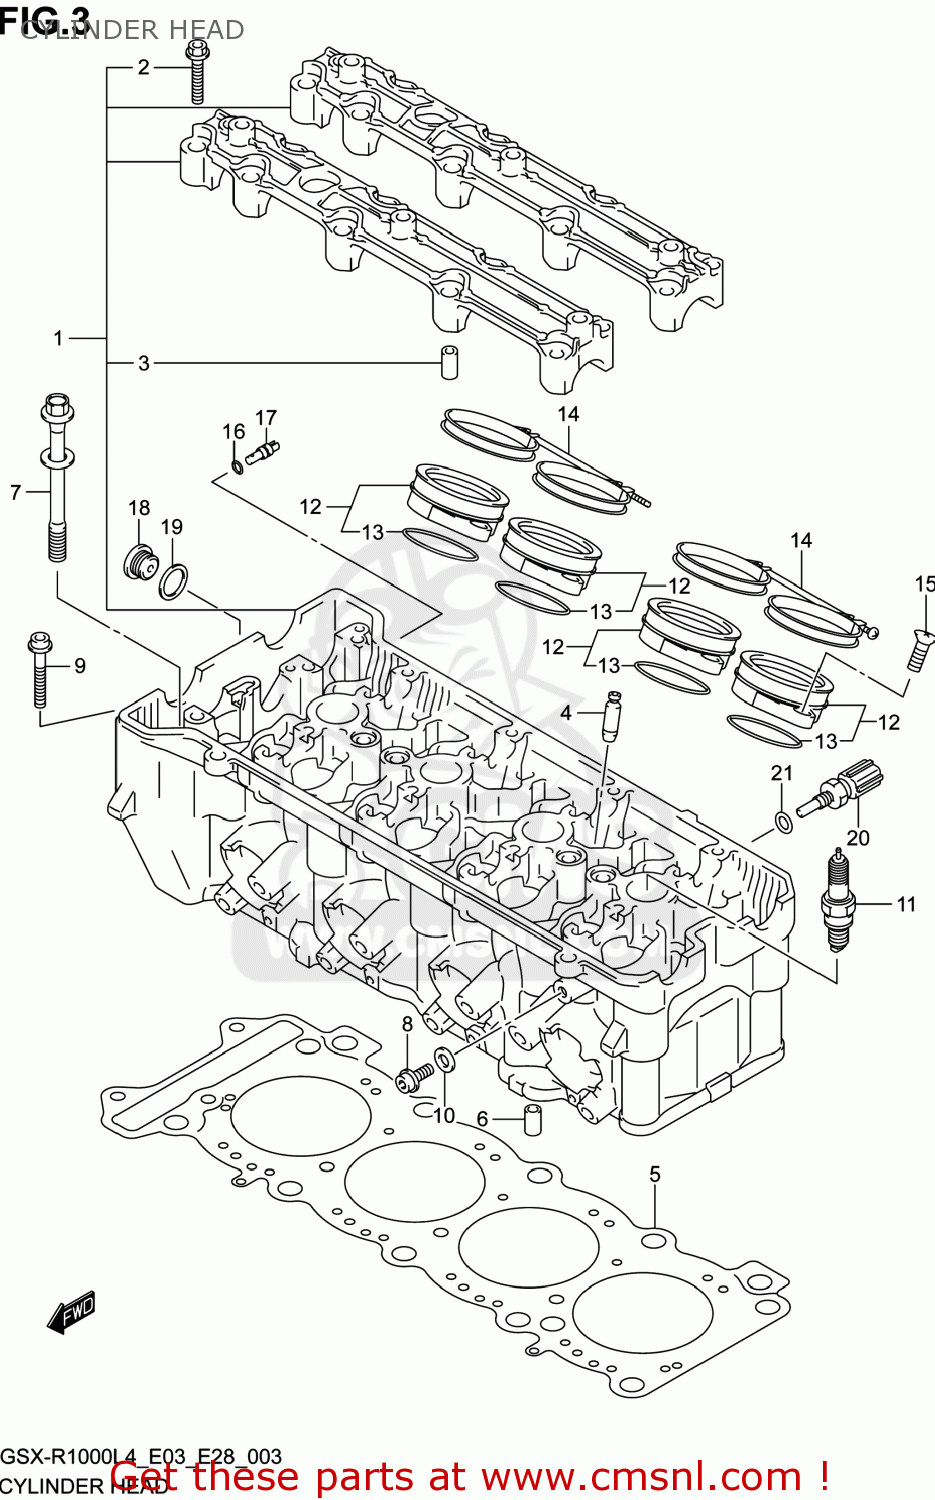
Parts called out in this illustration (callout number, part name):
1	HEAD ASSY,CYLINDER
2	BOLT(6X40)
3	PIN(6.2X8X16)
4	GUIDE,VALVE(OS:0.3)
5	GASKET,CYLINDER HEAD (NAS)
6	PIN
7	BOLT,CYLINDER HEAD(L:105)
8	BOLT(6X12)
9	BOLT
10	GASKET(5.8X13X1.2) (NAS)
11	PLUG,SPARK(IU27D)
12	PIPE ASSY,INTAKE
13	O RING(D:2.4,ID:47.2)
14	CLAMP,INTAKE PIPE
15	SCREW
16	O RING(D:1.2,ID:4)
17	JET,OIL GALLERY(16)
18	PLUG,16X8
19	GASKET(16X22X0.8) (NAS)
20	SENSOR,TEMP
21	GASKET(12X17X1) (NAS)
